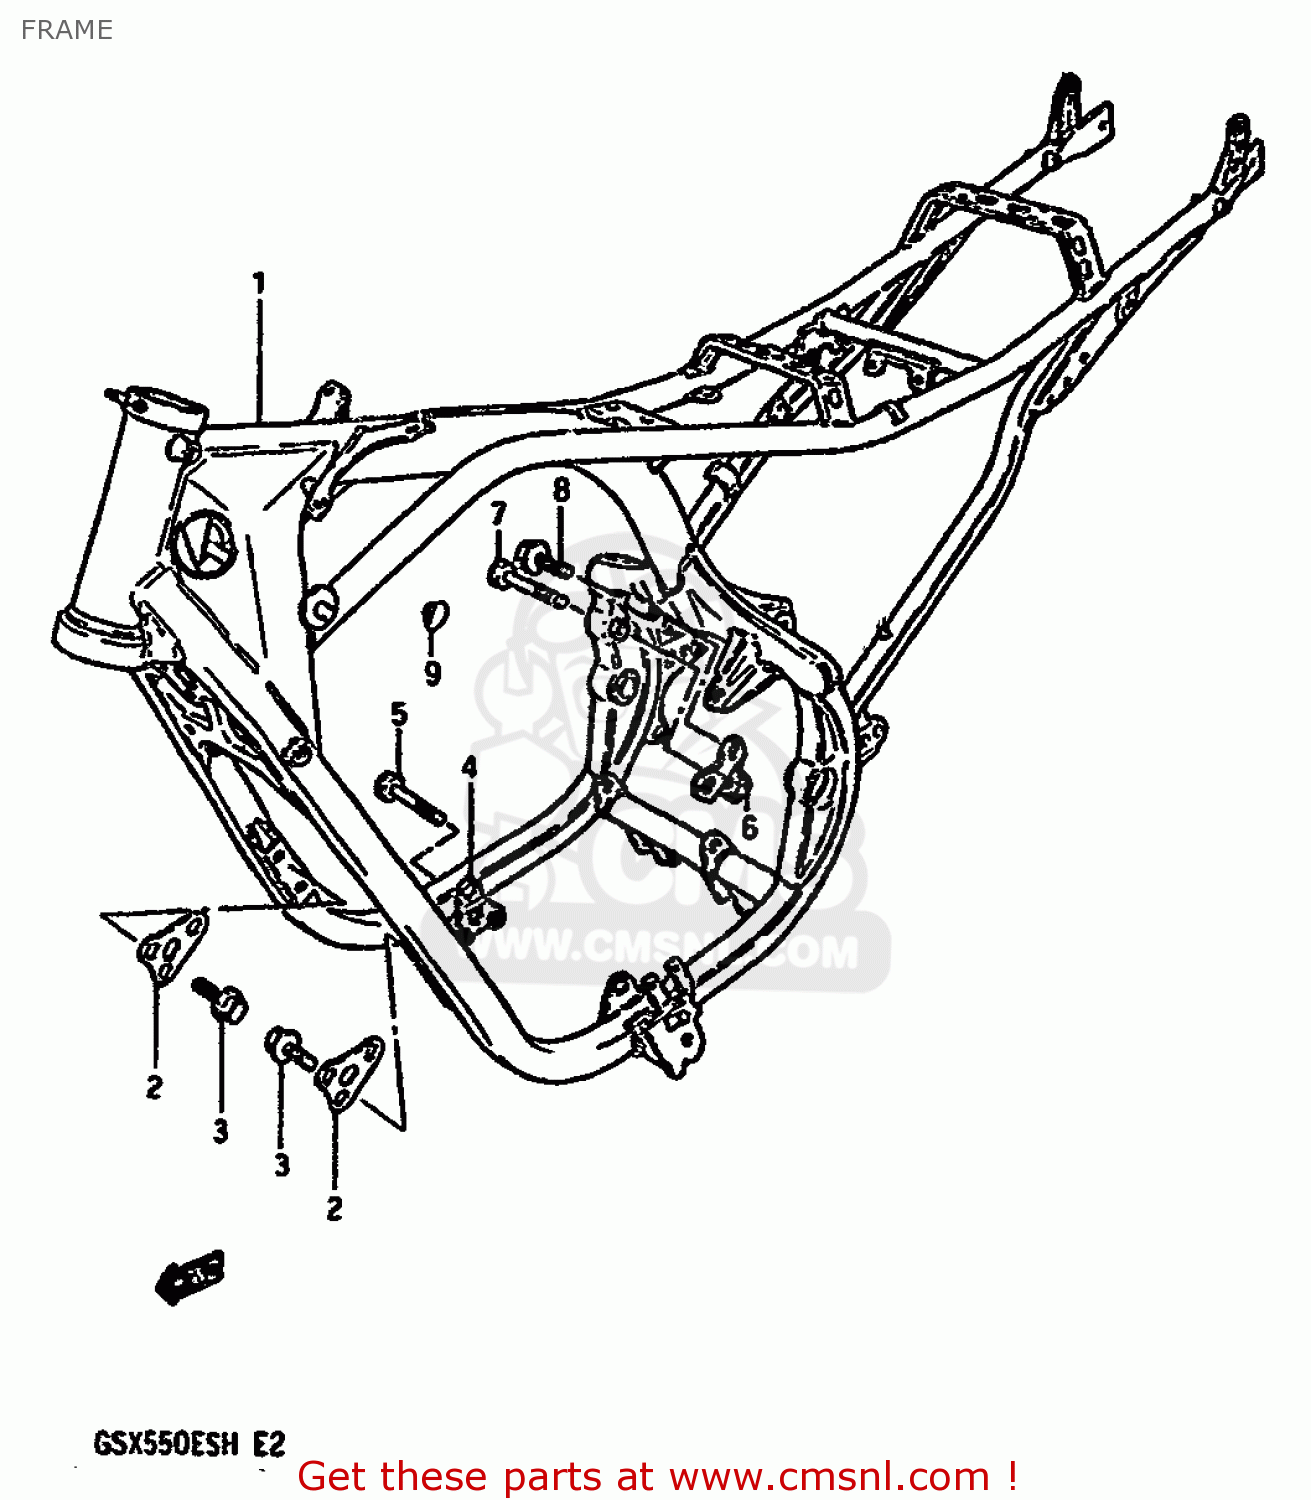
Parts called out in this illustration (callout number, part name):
1	FRAME (SILVER)
2	PLATE,ENGINE MOUNTING NO
3	BOLT 8X16
4	PLATE,ENGINE MOUNTING NO
5	BOLT
6	PLATE,ENGINE MOUNTING NO.4
7	BOLT
8	BOLT 8X16
9	PLUG
